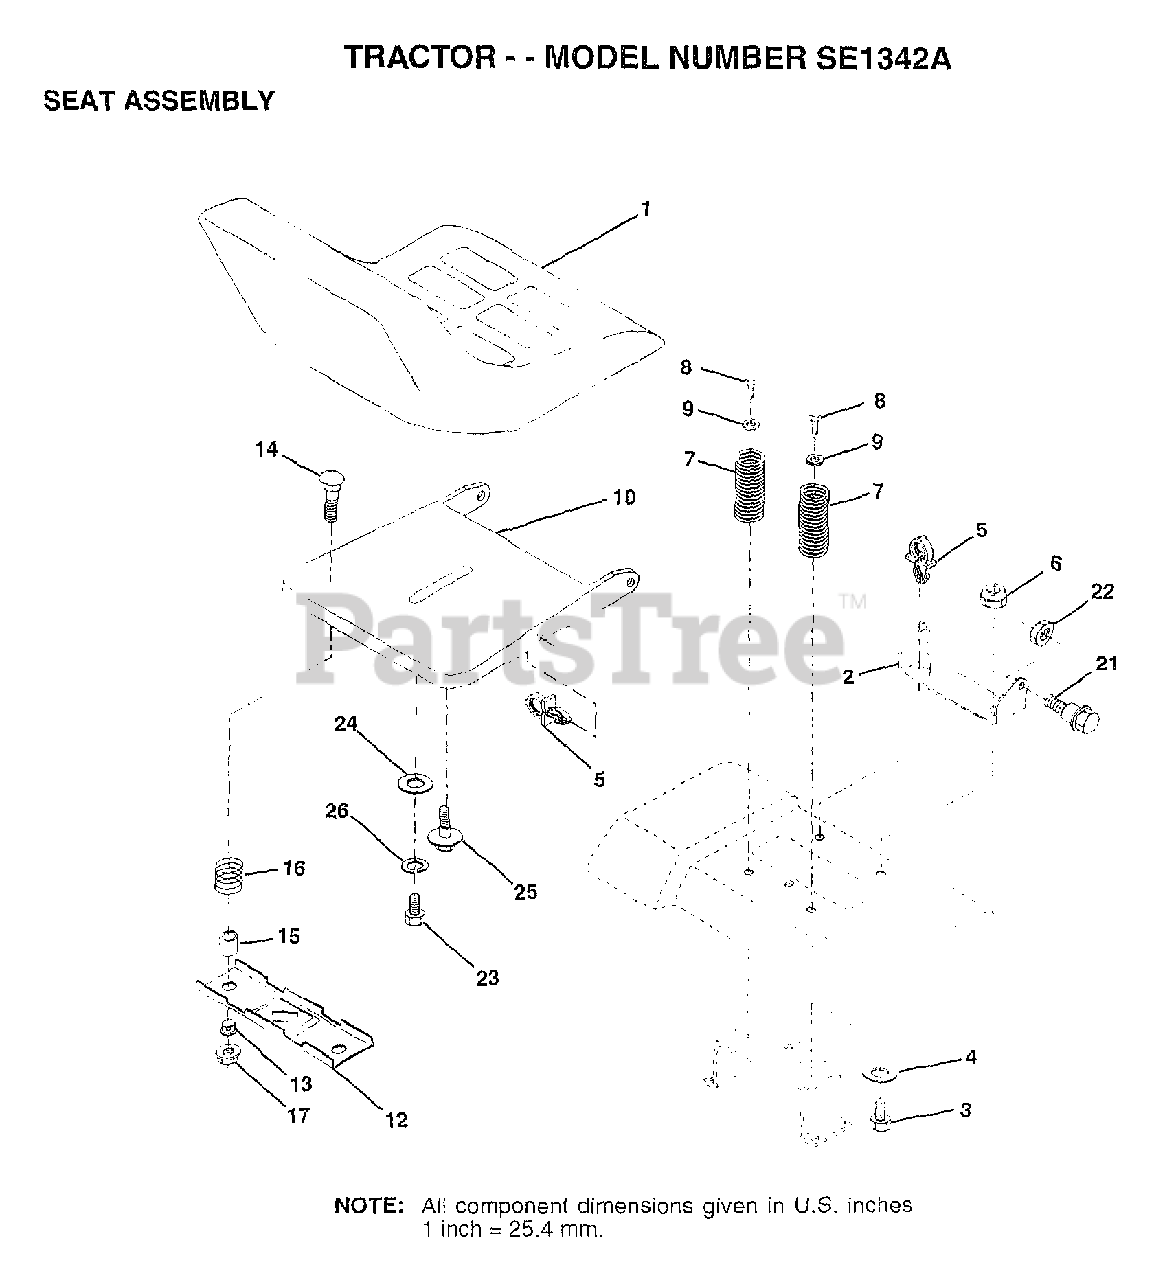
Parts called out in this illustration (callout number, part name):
1	SEAT.3300.BLK/BLK
2	BRACKET PVT SEAT
3	BOLT
4	WASHER PM
5	CLIP.PUSH-IN.HING
6	NUT
7	SPRING COMPRESSIO
8	SCREW GTV
9	WASHER
10	PAN-SEAT
12	BRKT SWITCH
13	BUSHING
15	SPLIT SPACER
16	SPRING
21	"BOLT,SHOULDER"
22	NUT
23	BOLT
24	WASHER
25	"BOLT,SHOULDER"
26	LOCKWASHER
